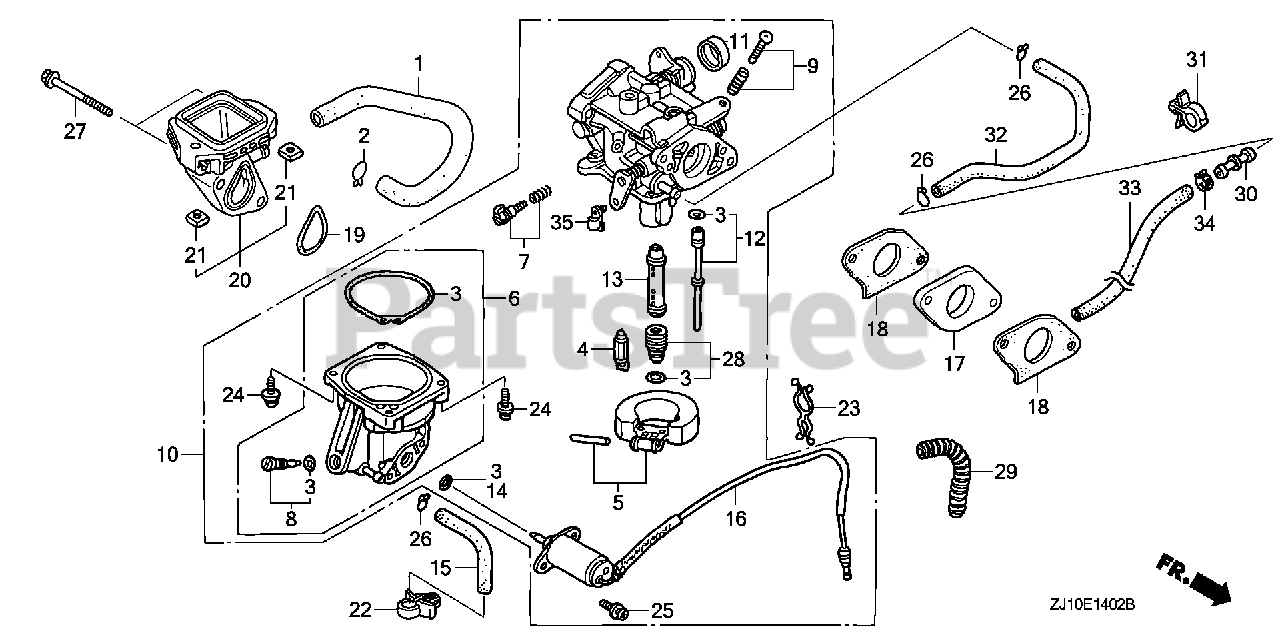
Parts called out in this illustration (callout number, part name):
1	TUBE, BREATHER
2	CLIP, BREATHER TUBE
3	GASKET SET
4	VALVE SET, FLOAT
6	CHAMBER SET, FLOAT
8	SCREW SET, DRAIN
10	CARBURETOR ASSY. (BG22G C)
11	CAP, CHOKE DUST
12	JET SET (#52)
13	NOZZLE, MAIN
14	O-RING (5.8X1.9)
15	TUBE, DRAIN
16	VALVE ASSY., SOLENOID
17	INSULATOR, CARBURETOR
18	GASKET, CARBURETOR
19	GASKET, AIR CLEANER
20	ELBOW, AIR CLEANER
21	NUT, INSERT (6MM)
22	CLIP B, CABLE (9MM BLACK)
23	CLIP, PURSE LOCK
24	SCREW-WASHER (4X14)
25	SCREW-WASHER (5X12)
26	CLIP, TUBE (B8)
27	BOLT, FLANGE (6X120)
28	JET SET, MAIN (#100)
28	JET SET, MAIN (#102)
28	JET SET, MAIN (#105)
32	BULK HOSE, FUEL (4.5X3000) (4.5X140)
35	ARM, THROTTLE LINKAGE
